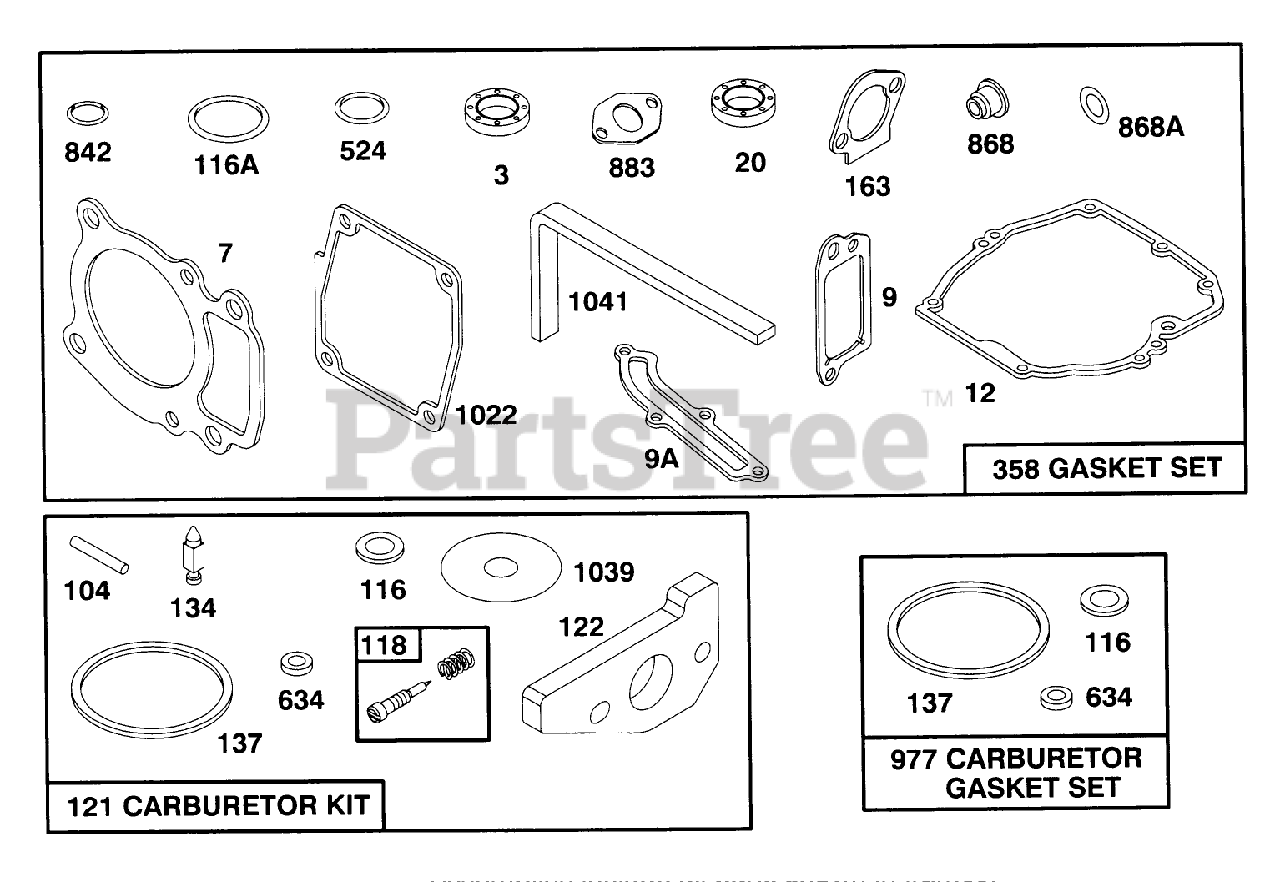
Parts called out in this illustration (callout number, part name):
7	CYLINDER HEAD GASKET
12	ENGINE BASE GASKET
20	SEAL-OIL
116	O RING SEAL
116A	SEALING GASKET
118	VALVE KIT - NEEDLE
121	CARBURATOR OVERHAUL KIT
122	ADAPTER ASSEMBLY
134	VALVE-FLOAT
137	FLOAT BOWL GASKET
163	AIR CLEANER GASKET
358	GASKET SET
524	O-RING
842	O-RING
977	CARBURATOR GASKET SET
1022	ROCKER COVER GASKET
1039	FLOAT LIMITER
